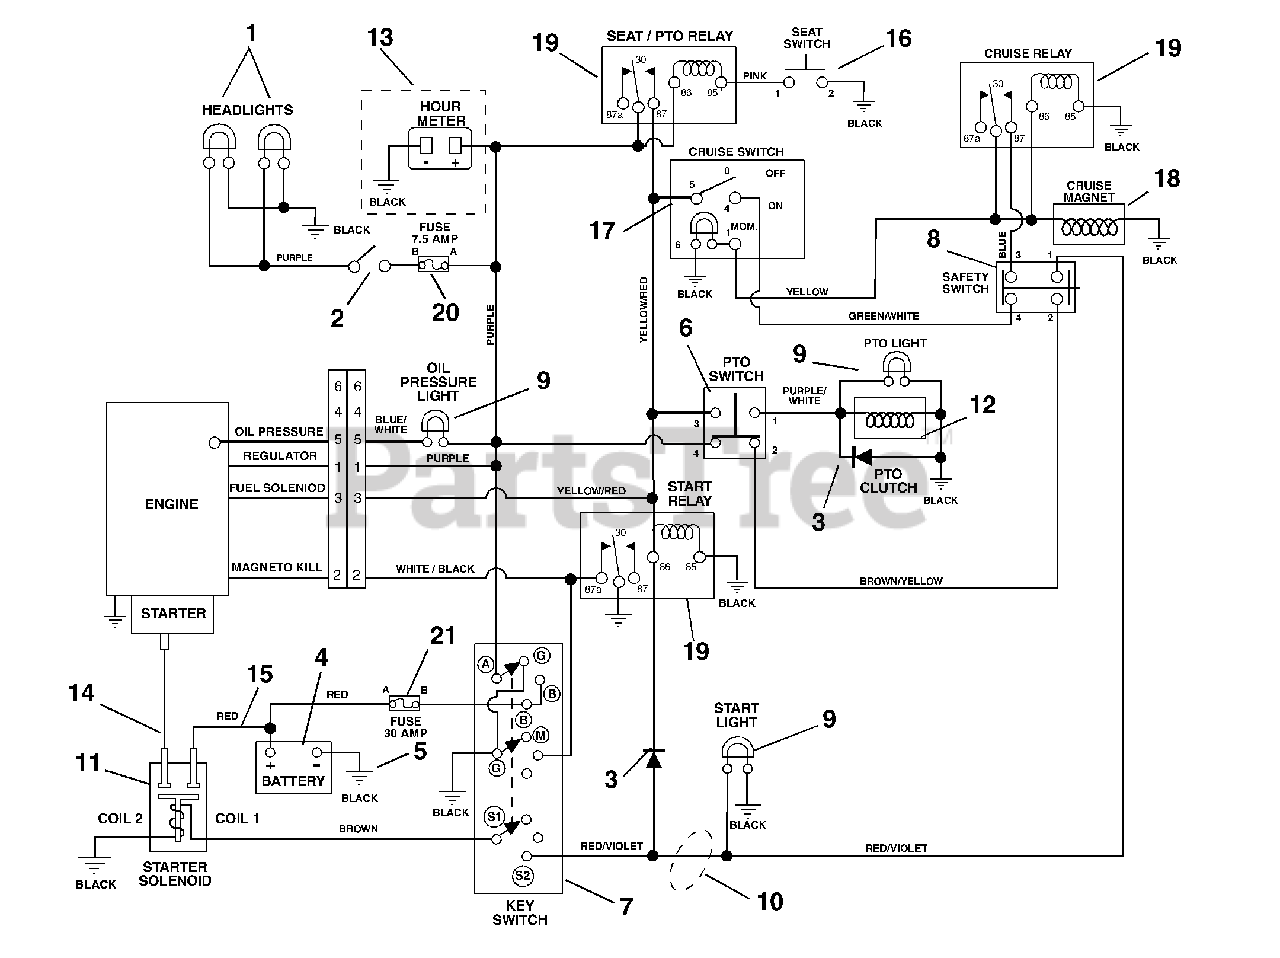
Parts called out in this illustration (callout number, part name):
1	HEADLIGHT BULB, 1156
2	SWITCH - LIGHT
3	MOLDED DIODE PLUG 1 AMP
4	BATTERY W/TUBE
5	GROUND CABLE .31X22.00X.31
6	PTO KNOB/ SWITCH ASSY
7	SWITCH KEY 5Y463A ALT GRDNG
8	SWITCH,INTERLOCK
9	BULB, #194
10	HARNESS-WIRING (INTEK TWIN)
11	SOLENOID
12	ELECTRIC CLUTCH/BRAKE (3.4AMP)
13	HOURMETER KIT- SIERRA
14	START CABLE 22"
15	STARTER CABLE 6.75"
16	SWITCH- SEAT
17	SWITCH - CRUISE
19	RELAY
20	FUSE, 7.5 AMP
21	FUSE, 30 AMP.
